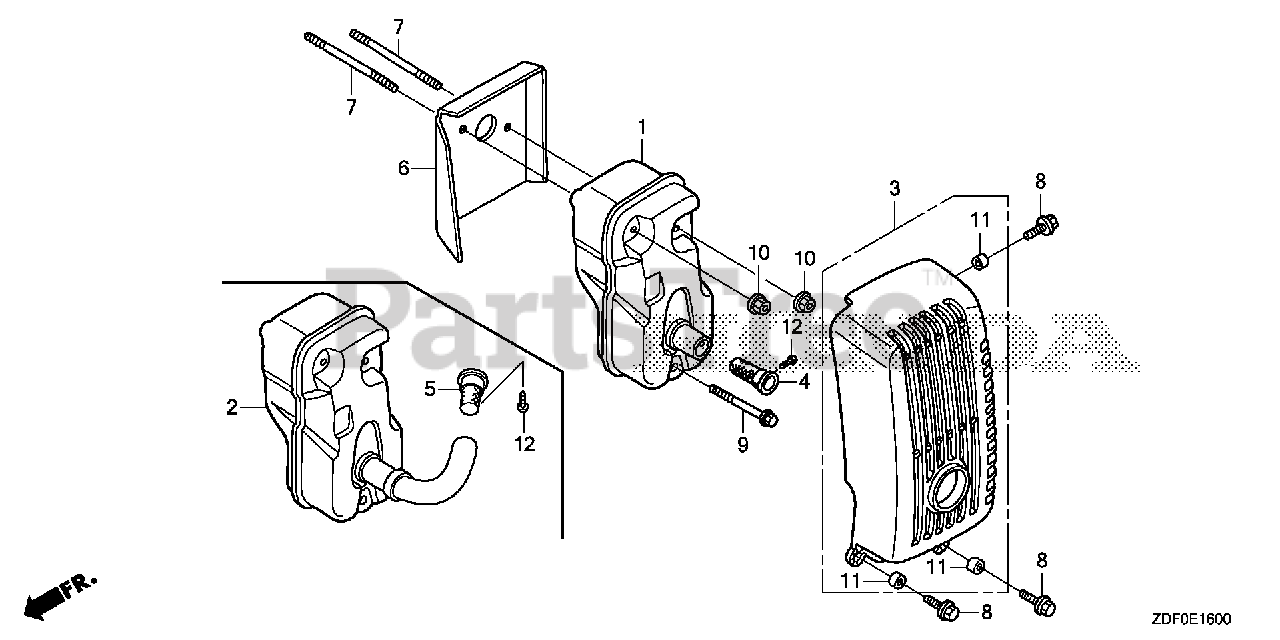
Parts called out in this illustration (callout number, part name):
3	PROTECTOR, MUFFLER
4	ARRESTER, SPARK
6	GUIDE, AIR
7	BOLT 2, STUD (5X55)
8	BOLT, FLANGE (5X16)
9	BOLT, FLANGE (5X35)
10	NUT, SELF-LOCK (5MM)
11	COLLAR, TOP COVER
12	SCREW, TAPPING (4X8)
